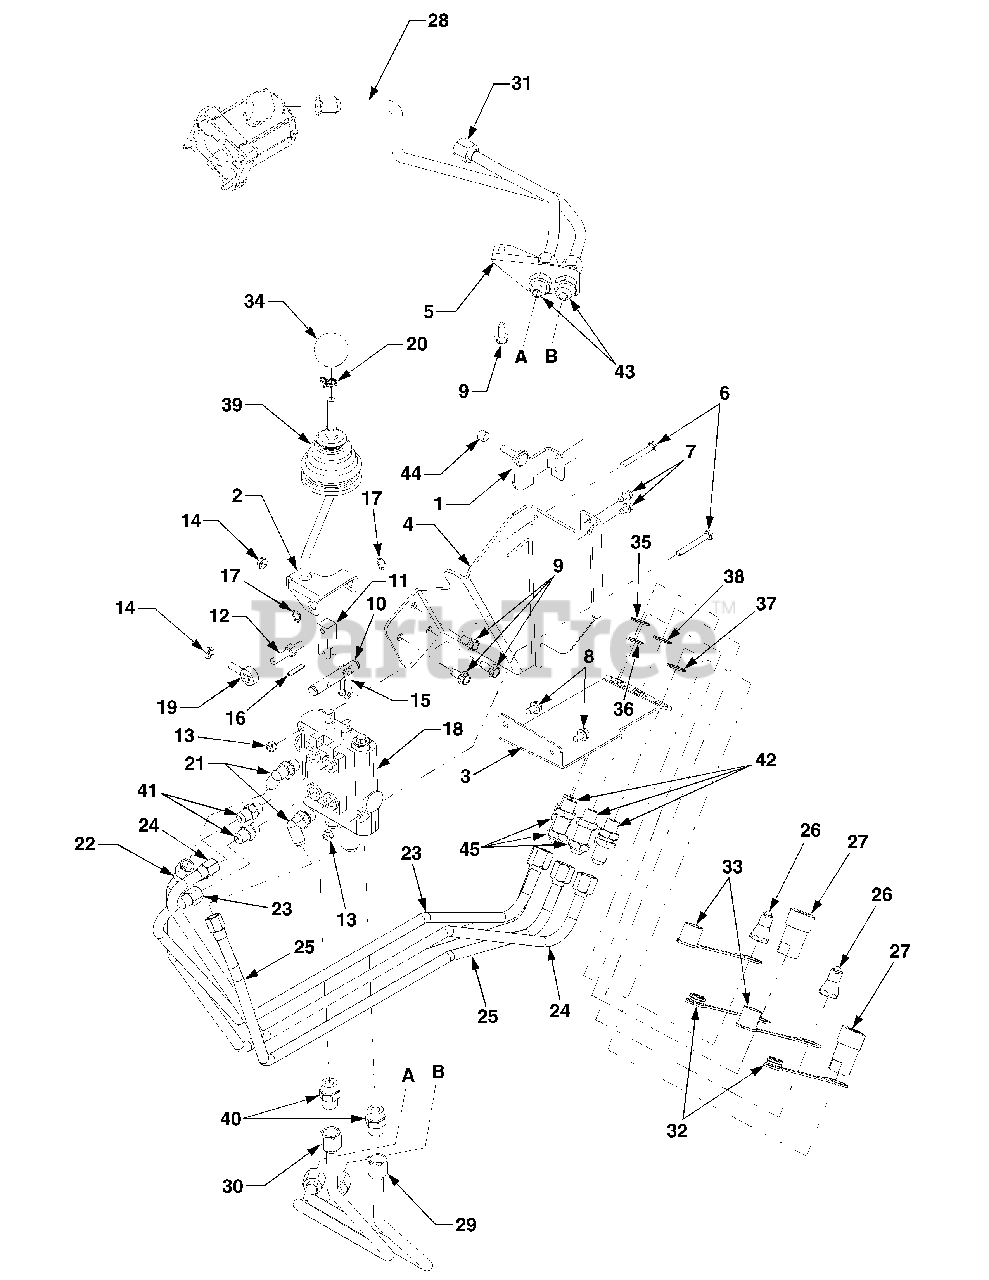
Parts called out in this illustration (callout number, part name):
1	Pivot Bracket Assembly
2	Valve Handle Assembly
7	Hex Wash. Hd. Tapp Screw 1/4-20 x .50
8	Hex Wash. Hd. Tapp Screw 5/16-18 x .625
9	Hex Wash. Hd. Tapp Screw 5/16-18 x .75
10	Valve Pivot Shaft
11	Valve Spool Link
12	Ball Joint Pivot Stud
13	Hex Insert Flange Lock Nut 1/4-20, GrF
14	Jam Nut, 5/16-24, Gr5
15	Chain Link
16	Spirol Pin, 3/16 x 1.0
17	Snap Ring, .5
18	Loader Control Valve
19	Ball Joint, .3125 ID x 5/16-24
20	Clamp, Hose
21	Fitting, 90 6-6 Orb
22	Tube, Hydraulic - Boom Lift - Original Style
22	Tube, Hydraulic - Boom Lift - New Style
23	Tube, Hydraulic - Boom Lower - Original Style
23	Tube, Hydraulic - Boom Lower - New Style
24	Tube, Hydraulic - Bucket Rollback - Original Style
24	Tube, Hydraulic - Bucket Rollback - New Style
25	Tube, Hydraulic - Bucket Dump - Original Style
25	Tube, Hydraulic - Bucket Dump New Style
26	Coupling, Male Hydraulic, 3/8-18
27	Coupling, Female Hydr. 3/8-18
28	Tube, Auxiliary Pump Pressure
29	Tube, Valve Pressure
30	Tube, Valve Return
31	Tube, Valve Return
32	Plug, Hydraulic Coupler - Male
33	Plug, Hydraulic Coupler - Female
34	Knob, 1.625 Dia x 3/8-16 Thd
35	Washer, Indicator - Red
36	Washer, Indicator - Yellow
37	Washer, Indicator - Green
38	Washer, Indicator - Blue
39	Joystick Boot
40	Fitting, Straight - 8 Orb
41	Fitting, Straight - 6 Orb
42	Fitting, Bulkhead w/ Jam Nut, 3/4-16 x 3/8-18 - Original Style
42	Fitting, Bulkhead 9/16-18 x 3/8-18 New Style
43	Fitting, Bulkhead 3/4-16 x 3/4-16
44	Spacer, .34 ID x .5 OD x .31
45	Nut, Jam, 9/16-18 Gr5 - New Style
